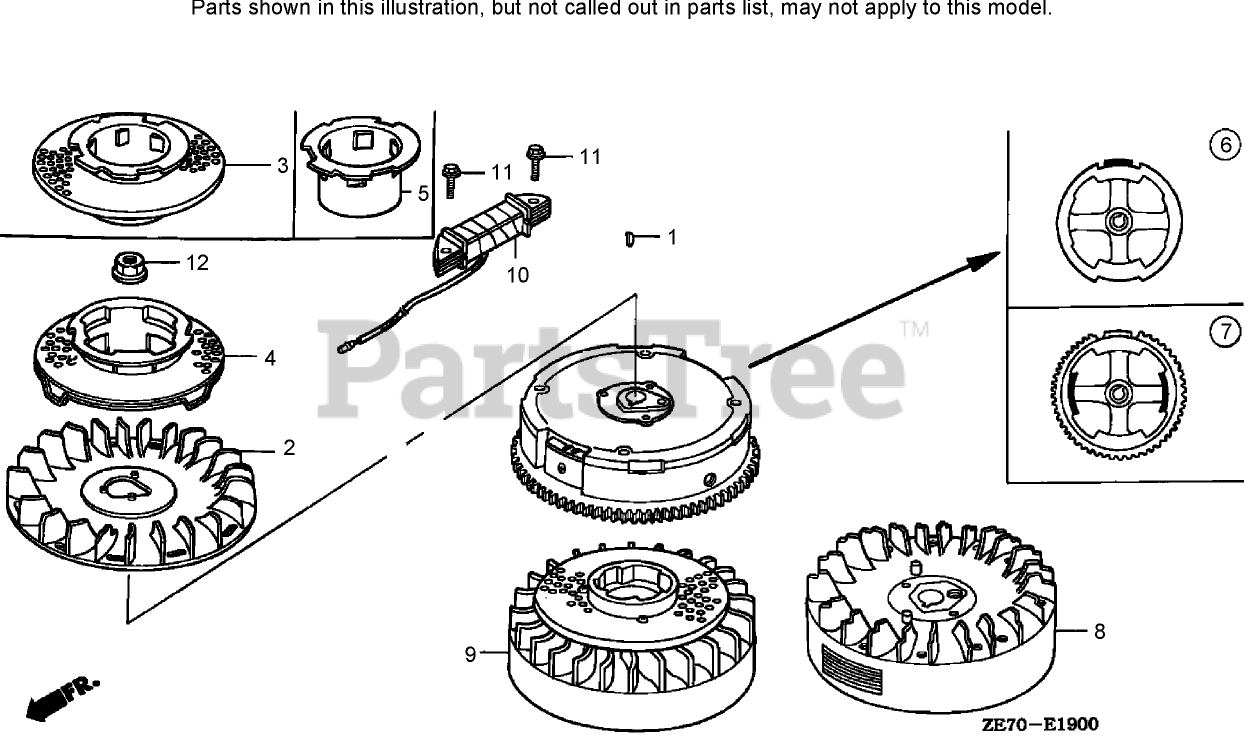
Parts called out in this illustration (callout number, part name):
1	KEY-WOODRUFF, SPECIAL (25X18)
2	FAN-COOLING
3	PULLEY-STARTER
6	FLYWHEEL (STD)
12	NUT-SPECIAL (14 mm)
